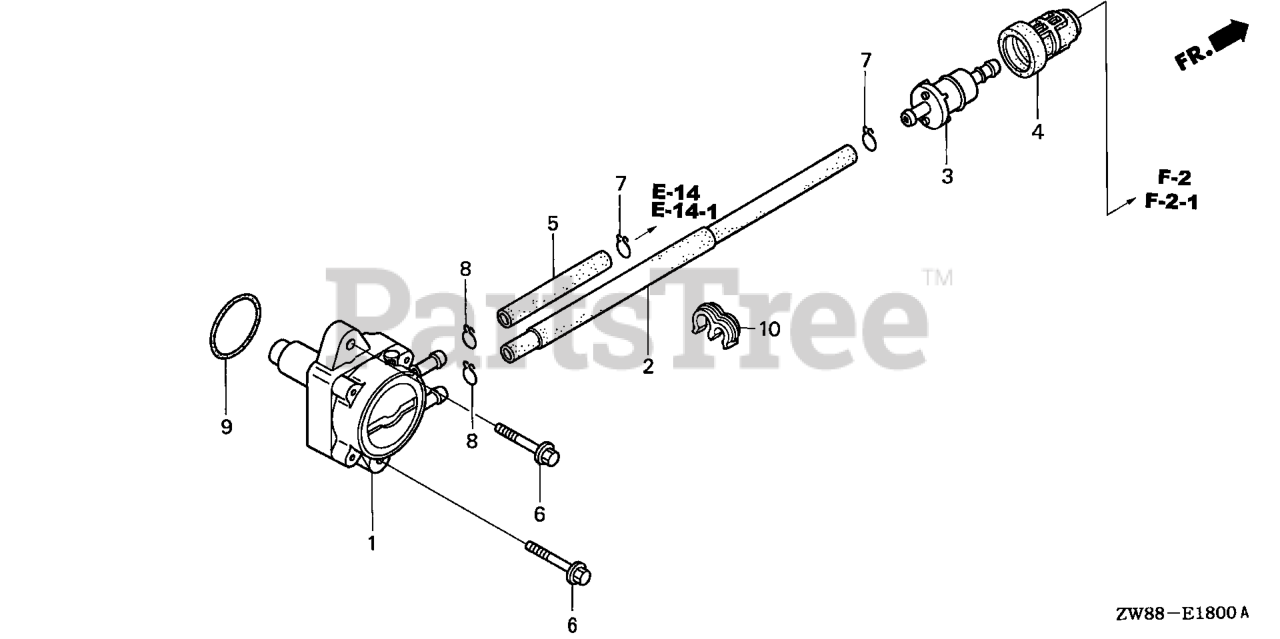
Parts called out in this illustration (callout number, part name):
1	PUMP ASSY., FUEL (MSDS)
2	TUBE B, FUEL
3	FILTER, FUEL
4	SUSPENSION, STRAINER
5	TUBE, FUEL
6	BOLT, FLANGE (6X22)
7	CLIP, TUBE (B10)
8	CLIP, TUBE (B12)
9	O-RING (31.2X2.4)
10	CLAMP, TUBE (7.5-11.5) (BLACK)
